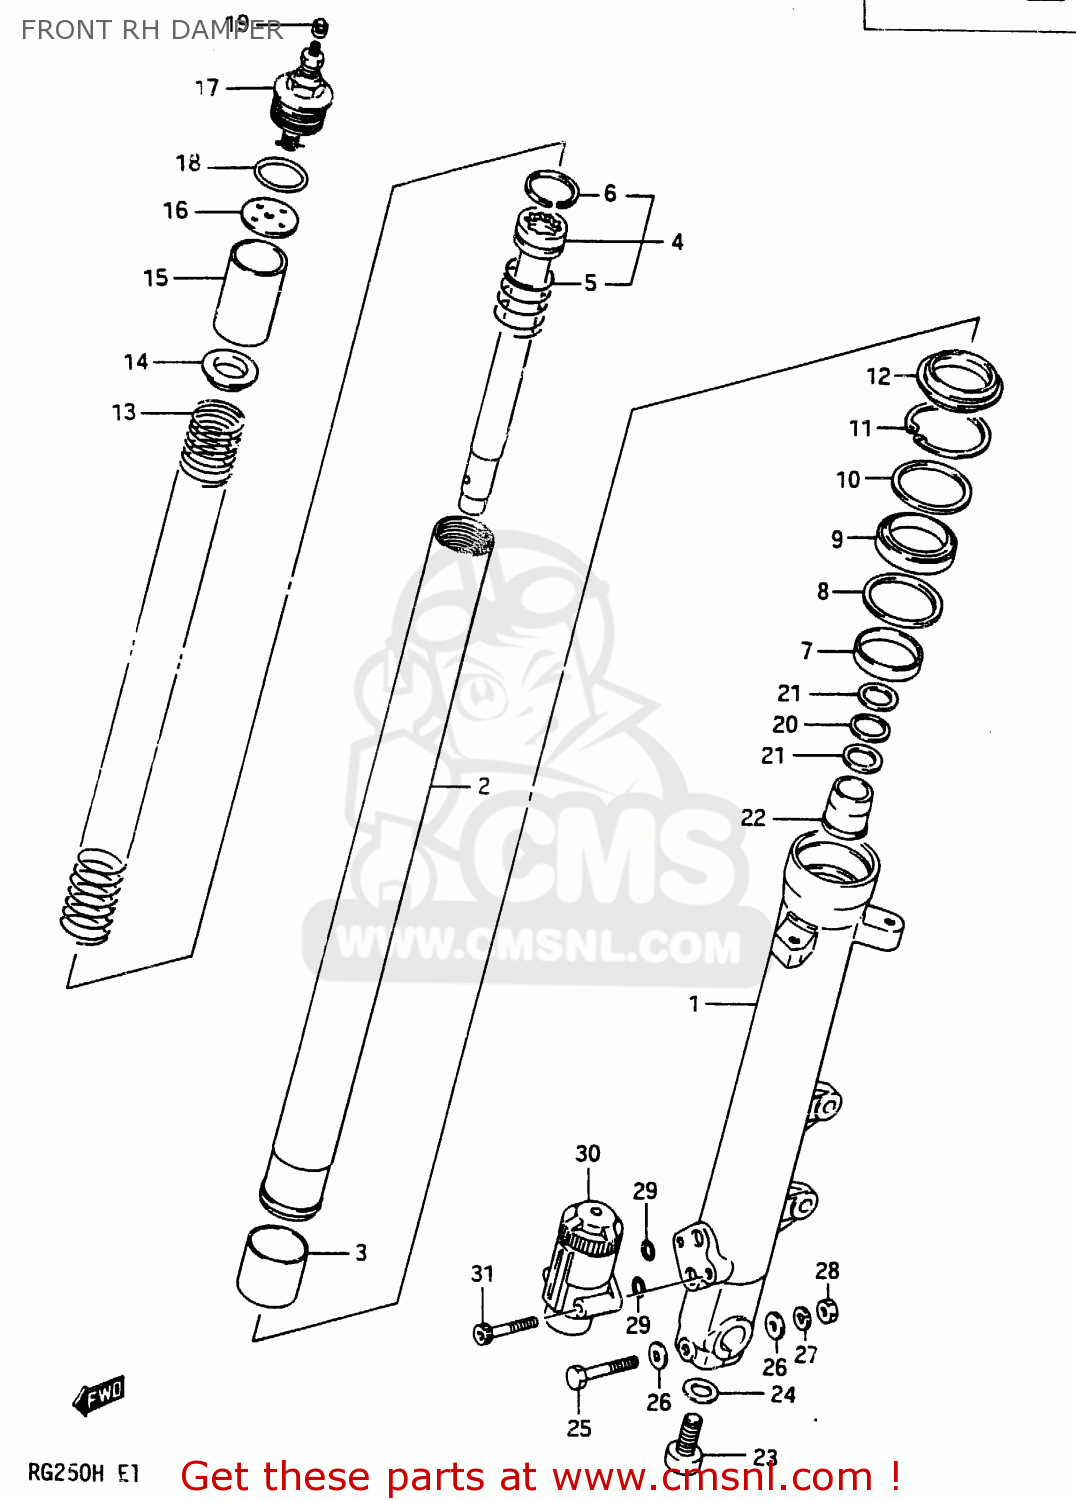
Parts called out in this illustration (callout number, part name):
1	TUBE, OUTER RH
2	TUBE, INNER
3	PISTON
4	CYLINDER
5	SPRING,REBOUND
6	RING,PISTON
7	METAL,SLIDE
8	WASHER,OIL SEAL INNER
9	SEAL,OIL
10	WASHER,OIL SEAL OUTER
11	12
12	SEAL,DUST
13	SPRING
14	GUIDE,SPRING
15	SPACER
16	WASHER
17	CAP
18	O RING
19	CAP,VALVE AIR
20	WASHER
21	SPRING,LEAF
22	PIECE,OIL LOCK
23	BOLT,FORK CYLINDER(10X25)
24	GASKET (NAS)
25	BOLT 8X55
26	WASHER
27	LOCK WASHER
28	NUT
29	O RING
30	P.D.F. ASSY
31	BOLT
